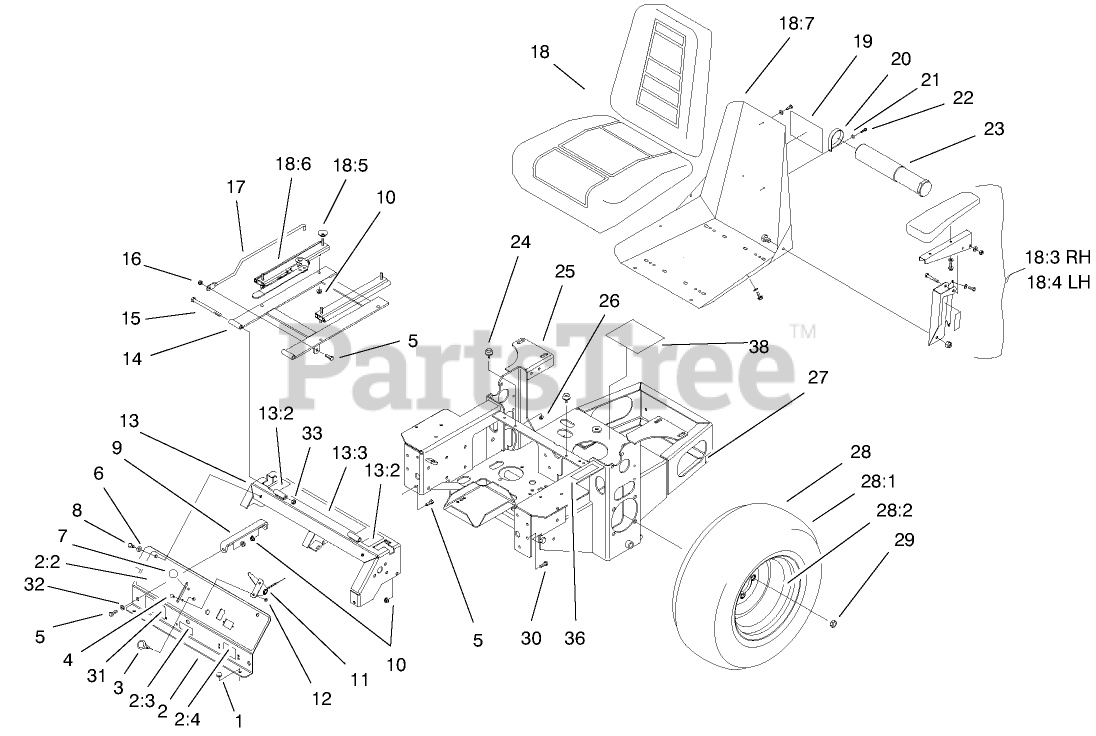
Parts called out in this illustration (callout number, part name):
1	Bumper
2	CONTROL PANEL ASM
2:2	DECAL-PANEL, CONTROL
2:3	Decal-Fuel Valve
2:4	DECAL-PROTECTION, EAR
3	Cable-Choke
4	Bolt-CARR
5	SCREW-HH
6	WASHER-PLAIN
7	Knob
8	SCREW-HH
9	Bracket-Panel,Instrument
10	NUT-HF
11	Cable
12	NUT-LOCK, NI
13	CONSOLE ASM
13:2	Decal-Motion Control
13:3	Decal-Battery
14	Frame-Seat
15	SCREW-HH
16	NUT-LOCK, NI
17	Rod-Hold Up, Seat
18	Seat ASM
18:3	Armrest
18:4	Armrest
18:5	Spacer-Track
18:6	Track-Locking
18:7	Frame-Seat
19	DECAL
20	CLAMP-R
21	WASHER-FLAT
22	SCREW-HWHTF
23	TUBE-MANUAL
24	Bumper
25	Frame-Main
26	NUT-HF
27	DECAL-SURFACE, HOT
28	Wheel And Tire ASM
28:1	Tire
28:2	Wheel
29	Nut
30	SCREW-HH
31	DECAL-Z153
32	WASHER-FLAT
33	NUT-LOCK, NI
36	Decal-Drive Wheel
38	Decal Hazardous Mat.
